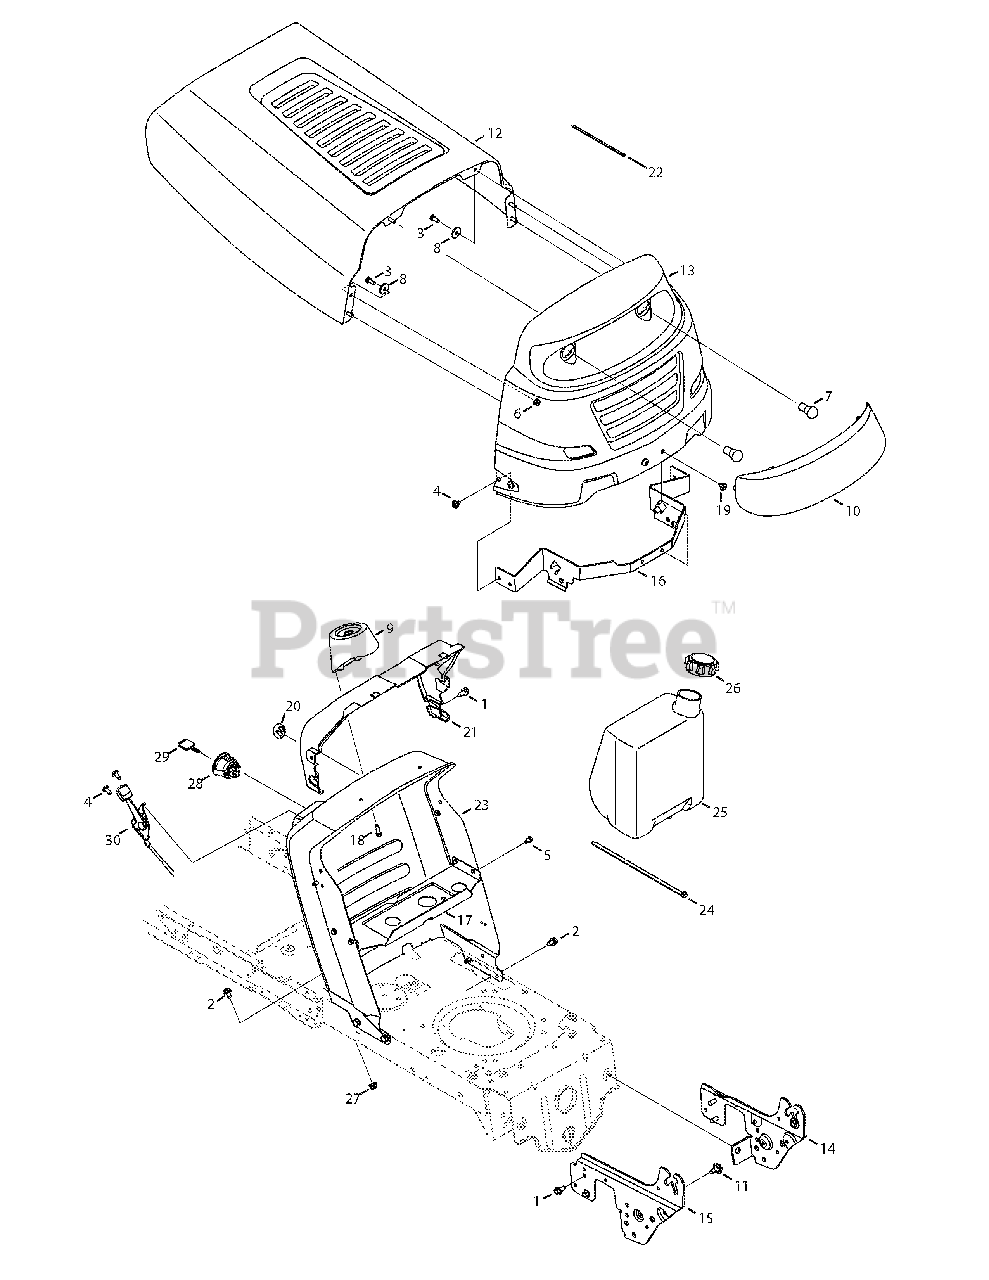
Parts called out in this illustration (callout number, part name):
1	Self-Tapping Screw 5/16-18 x .750
2	Screw, 5/16-18, 0.625
3	Screw, 1/4-20, .620, Gr5
4	Screw, 1/4-20, .500
5	Screw, 1/4-20, 0.500
6	Nut, Flange Lock, 1/4-20, Gr5
7	Headlamp, 12V
8	Washer, Flat, .265 x .938 x .120
9	Support, Steering
11	Screw, Shoulder, .43 x.29, 5/16-18
18	Screw, 1/4-15, 0.750
19	Self-Tapping Screw 5/16-18 x .375
20	Dash Plug
21	Collar, Dash
22	Cable Tie
24	Cable Tie, 34.75
25	Fuel Tank, 1.5 gal.
26	Fuel Tank Cap
27	Flange Lock Nut 5/16-18
28	Igntion, Switch (No RMC) 3 Position
29	Key
30	Throttle/Choke Control, 25"
